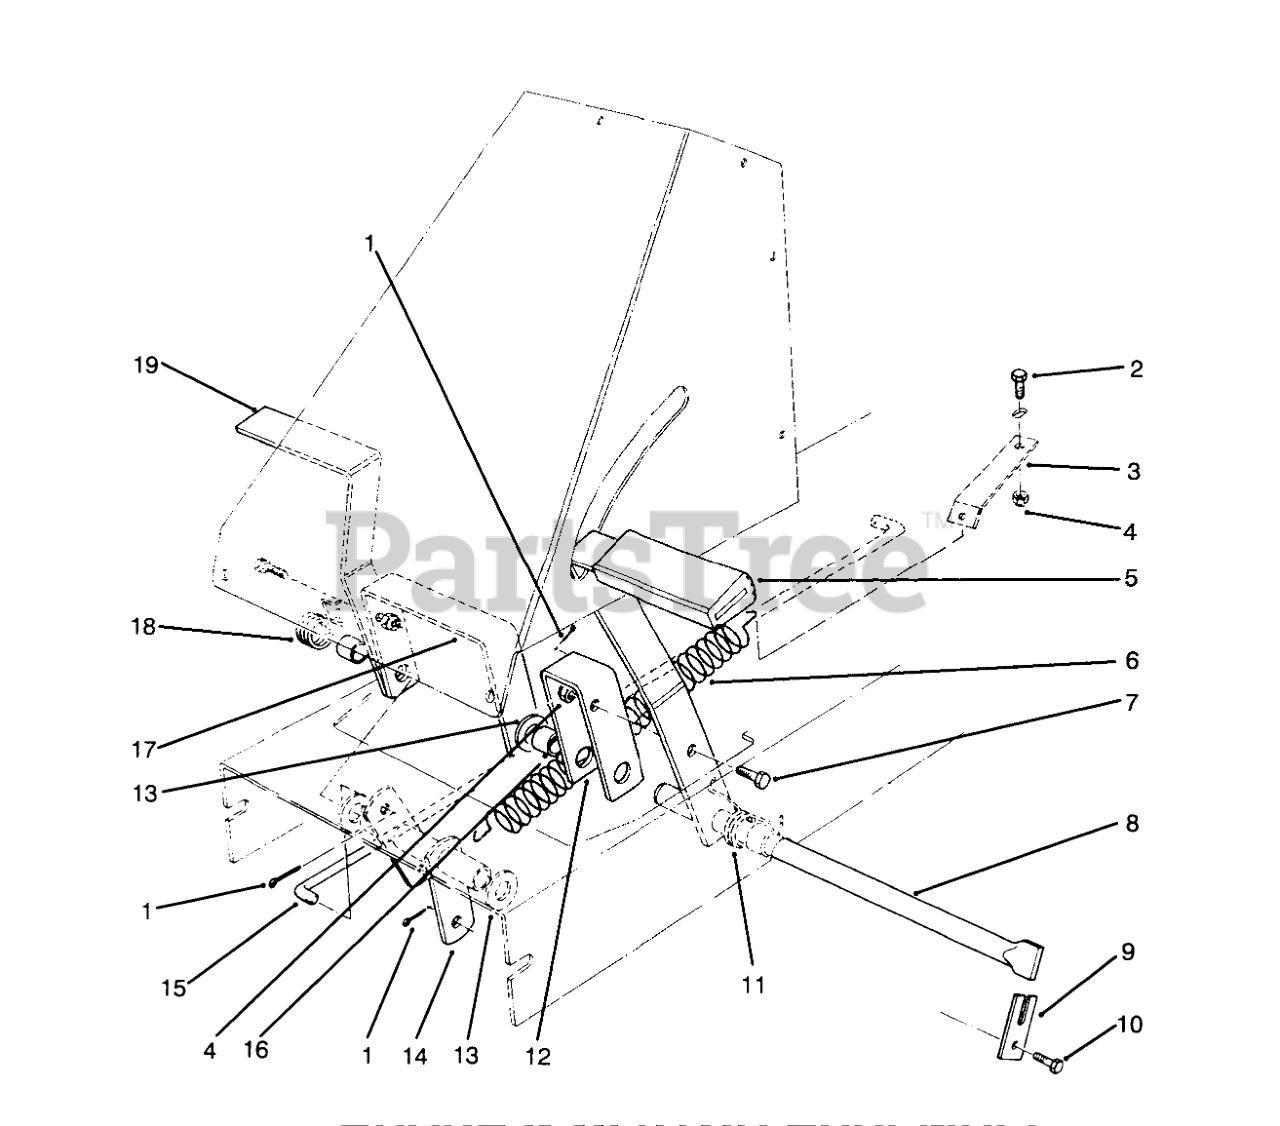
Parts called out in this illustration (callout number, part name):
1	PIN-COTTER
2	SCREW-HH
3	BRKT-SPRING RET
4	NUT-LOCK, NI
5	PAD-PEDAL
6	SPRING-EXTENSION
7	SCREW-HH
8	SHAFT-PEDAL PIVOT
9	RETAINER-SHAFT
10	SCREW-HH
11	SPRING-TORS CLUTCH
12	Bracket-Clutch Pedal
13	WASHER-FLAT
14	Pivot Tube
15	ROD-ENGAGE
16	SPACER-PEDAL
17	Bracket-Brake Pedal
18	SPRING-TORS BRAKE
19	Pedal
